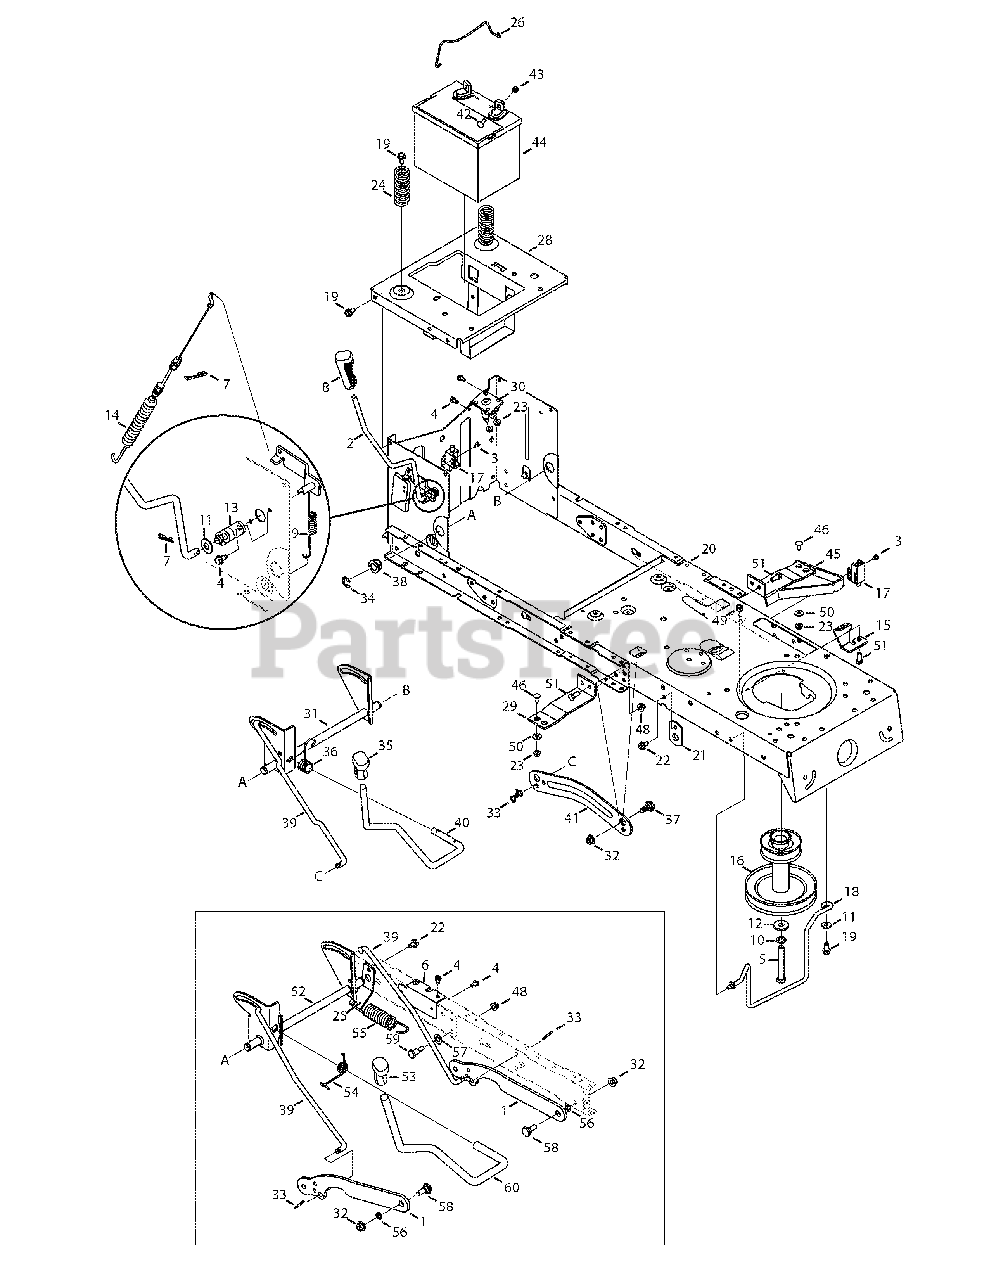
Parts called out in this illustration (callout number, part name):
3	Shoulder Screw, #10-16, 0.500
4	Screw, 1/4-20, 0.500
5	Screw, 7/16-20, 3.25 38 &42" Dk.
7	Pin, Click, .092 x 1.64
8	Grip, Handle, 3/8
9	Spring, Extension
10	Washer, Lock, 7/16
11	Washer, Flat, .406 x .875 x .059
12	Washer, Flat, .450 x 1.250 x .164
13	Bearing, PTO
14	Cable, Deck Engagement
16	Engine Pulley, 38" & 42" Deck
17	Switch, Interlock
18	Rod, Belt Keeper (38" Deck)
19	Screw, 5/16-18, .750
22	Screw, 5/16-18, 0.625
23	Nut, Flange Lock, 1/4-20, GrF
24	Spring, Compr. , 1.28 OD x 3.125
25	Lift Bracket
30	Solenoid
32	Nut, Flange Lock, 3/8-16, GrF
33	Pin, Cotter .08 x 1.56 Intern. RH
34	Ring, E-Type, .625 Dia.
35	Grip, Handle, 1/2
36	Spring, Torsion 38/42" Decks
37	Screw, Shldr. , .625 x .175, 3/8-16
38	Bearing, Hex Flange
39	Rod, Lift
40	Deck Handle, Lift, 38/43" Decks
42	Screw, Carriage, 1/4-20, .75, Gr5
43	Nut, Sems, 1/4-20
44	Battery, 190 CCA
46	Carriage Screw, 1/4-20 x .62
47	Screw, 5/16-18 x .625
48	Flange Lock Nut, 5/16-18
49	Hex Lock Nut, 5/16-18
50	Flat Washer, .28 x .74 x .063
51	Hex Screw, 5/16-18 x .75
53	Grip, Handle, 5/8
54	Spring, Torsion 46" Deck
55	Extension Spring
56	Washer, Flat, .385 x .62 x .063
57	Washer, Flat, .474 x .879 x .064
58	Bolt, Shldr. .500 x .270 3/8-16
59	Screw, Shldr. , .437 x .54
60	Deck Handle, Lift, 46" Deck
